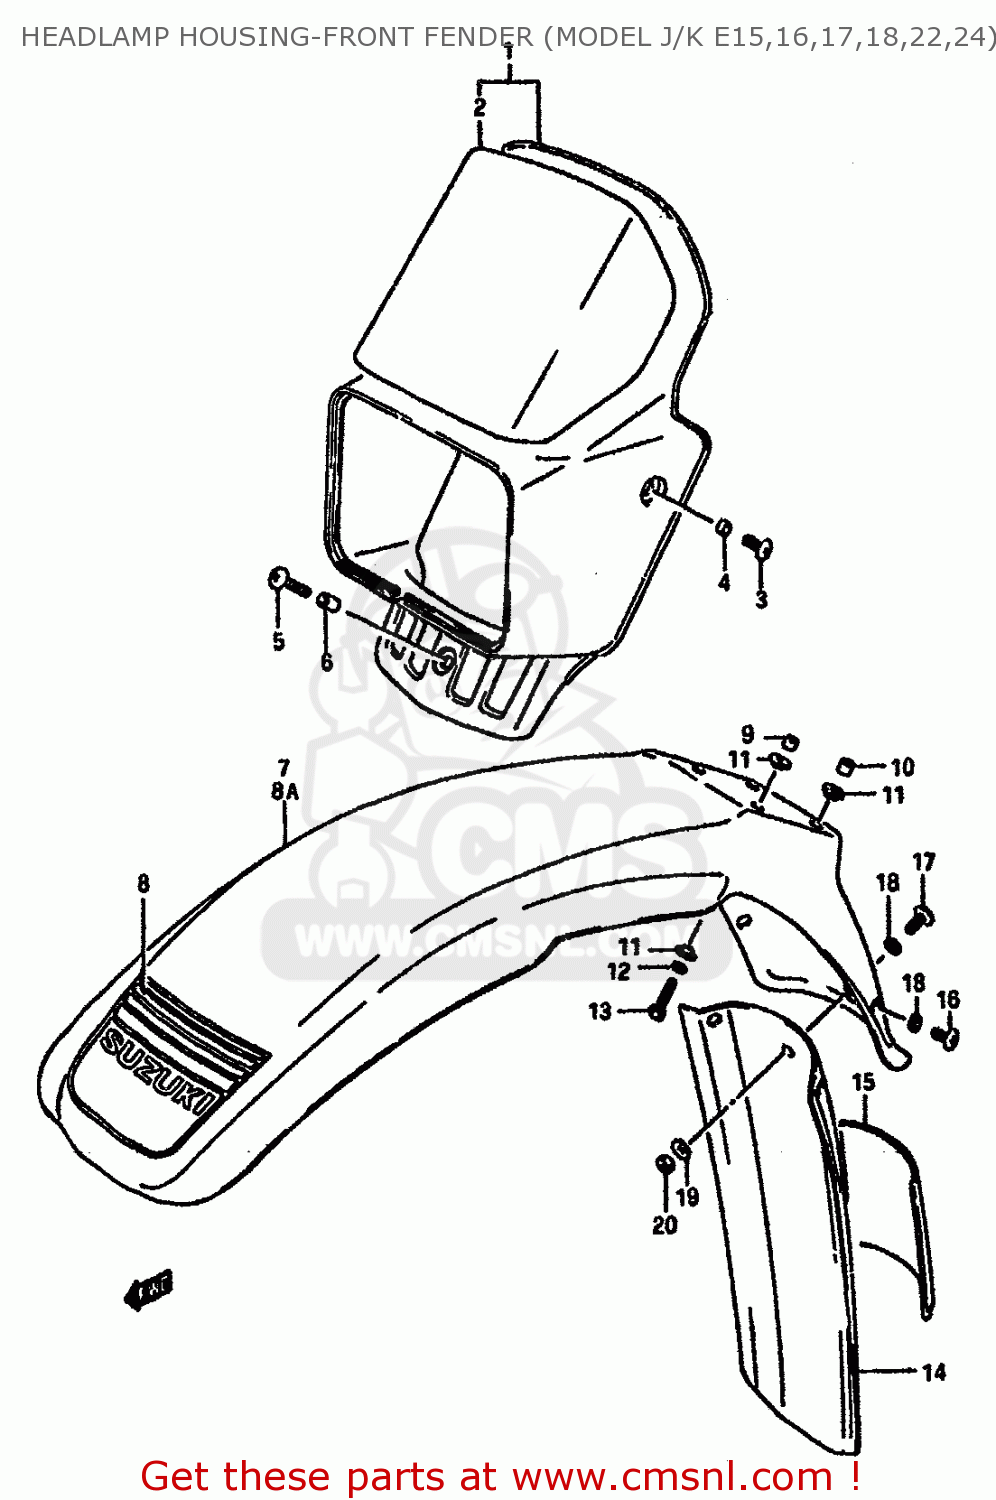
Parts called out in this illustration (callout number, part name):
1	COVER,HEADLAMP
2	TAPE SET
3	SCREW 6X12
4	SPACER (6.1X8X3.5)
5	SCREW, CENTER
6	SPACER (6.1X8X12)
7	FENDER,FRONT (BLUE)
8	TAPE,FR FENDER
8A	FENDER,FRONT
9	SPACER(6.1X9X7.5)
10	SPACER (6.8X10X10)
11	WASHER
12	WASHER,LOCK
13	BOLT
14	MUD FLAP, FRONT FENDER
15	TAPE SET
16	SCREW
17	SCREW, CENTER
18	SPACER
19	WASHER,LOCK
20	BOLT
21	MUD FLAP
22	PROTECTOR SEAT
23	SCREW
24	SCREW, CENTER
25	WASHER,LOCK
26	WASHER (6.7X16X1.8)
27	NUT 6MM
